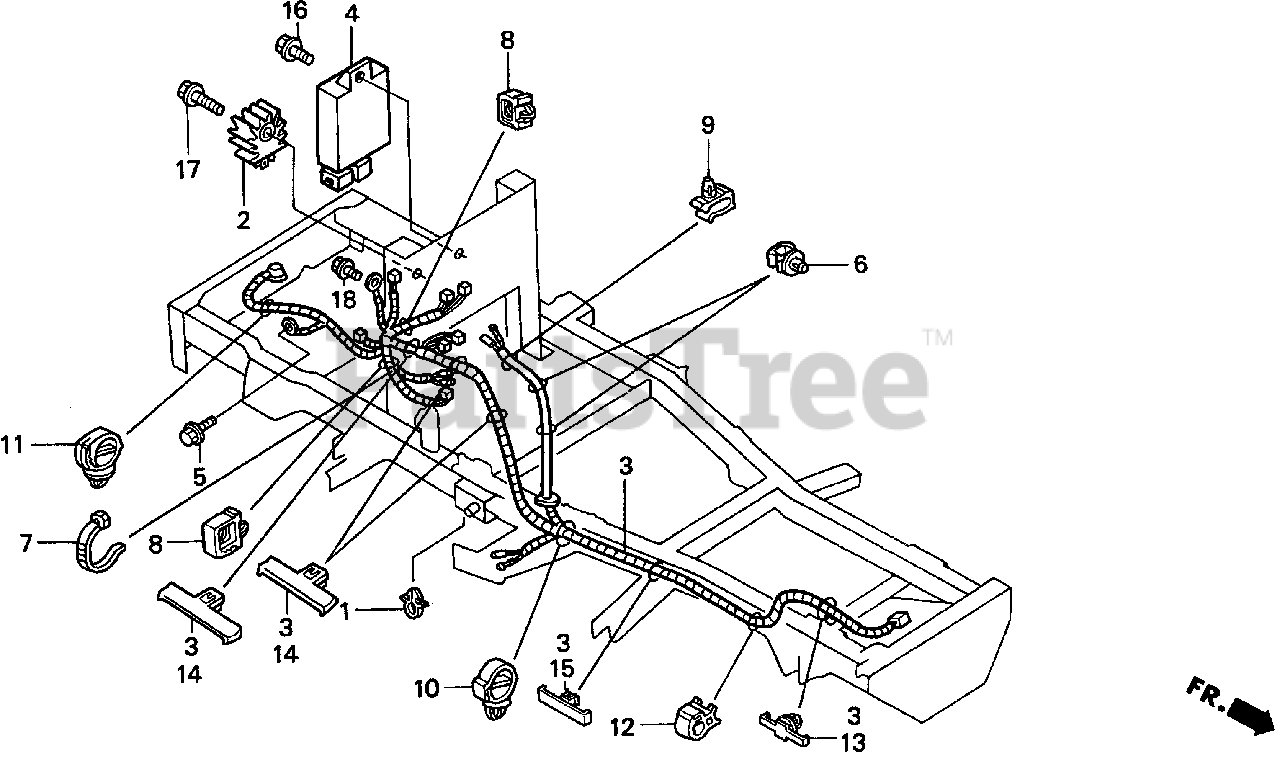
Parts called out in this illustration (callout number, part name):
1	CLIP, IGNITION WIRE (BLACK IN.D=7.0MM)
2	RECTIFIER, REGULATE
3	WIRE HARNESS ASSY., MAIN (NOT AVAILABLE)
3	WIRE HARNESS ASSY., MAIN
4	RELAY ASSY., COMBINATION
5	BOLT, GROUND (6X12) (SN)
6	CLIP, WIRE HARNESS
7	BAND, WIRE (165MM) (BLACK)
8	CLIP, HARNESS (10MM)
9	CLIP, CORD
10	CLIP, WIRE HARNESS
11	CLIP, WIRE HARNESS (25MM)
12	CLIP, CABLE (8MM)
13	CLIP, WIRE HARNESS (50MM) (GRAY)
14	CLIP, WIRE HARNESS
15	CLIP, WIRE HARNESS (BLACK)
16	BOLT, FLANGE (6X12) Use up to Engine SN 1543277.
17	BOLT, FLANGE (6X30)
